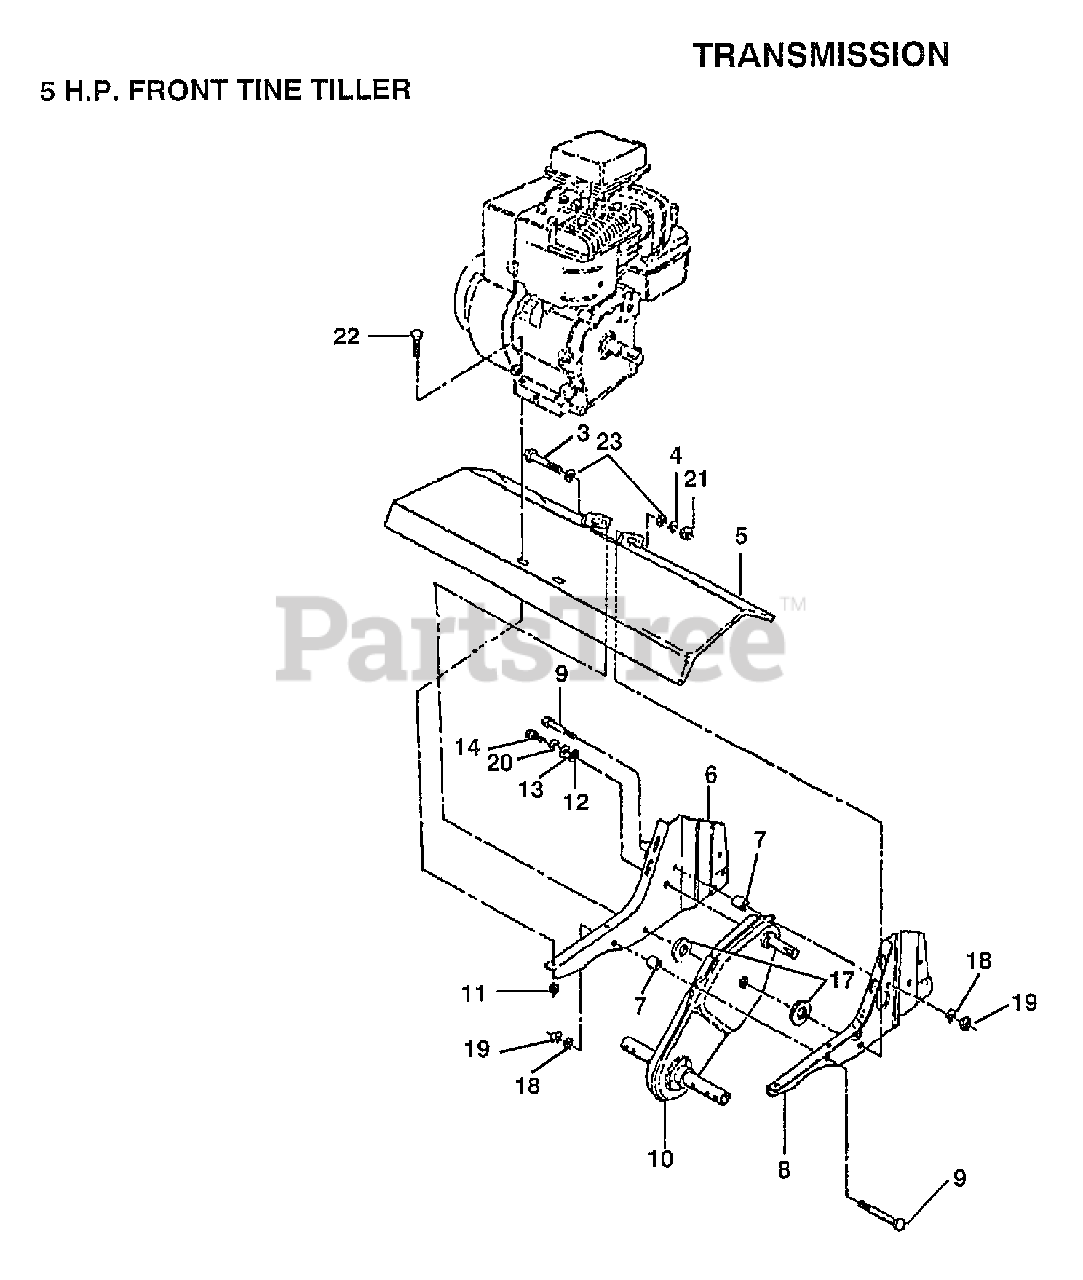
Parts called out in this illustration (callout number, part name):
3	BOLT.3/8-24X3.75
4	LOCKWASHER
7	SPLIT SPACER RT
8	BRACKET.ENG.LH.
12	WASHER
13	WASHER
14	BOLT
18	LOCKWASHER
19	NUT.HEX.5/16-18
20	LOCKWASHER
21	GRIPCO NUT
22	BOLT.HEX.5/16-1.5
23	WASHER
